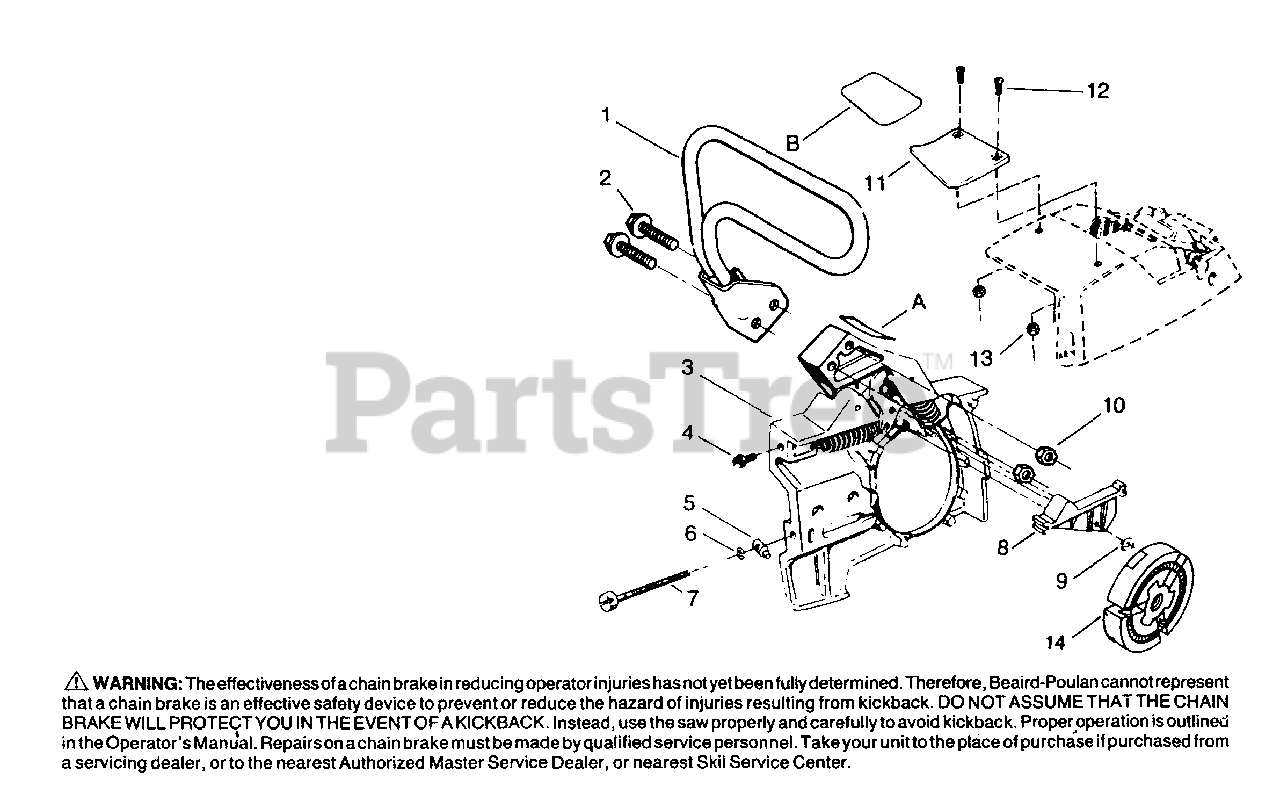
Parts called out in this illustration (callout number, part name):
1	Handle- Actuating Arm
2	Screw-Handle
3	Bar Clamp Actuating Arm Ass'y.
4	Screw-Adjusting
5	Pin - Bar Adjusting
6	"E" Ring
7	Screw - Bar Adjusting
8	Guard
9	Retaining Ring
10	Nut-H10-24
11	Shield - Heat
12	Screw - #10 - 24 x 1/2
13	Nut-#10-24
14	Clutch
A	Decal - Warning
B	Decal - Instruction (Heat Shield)
